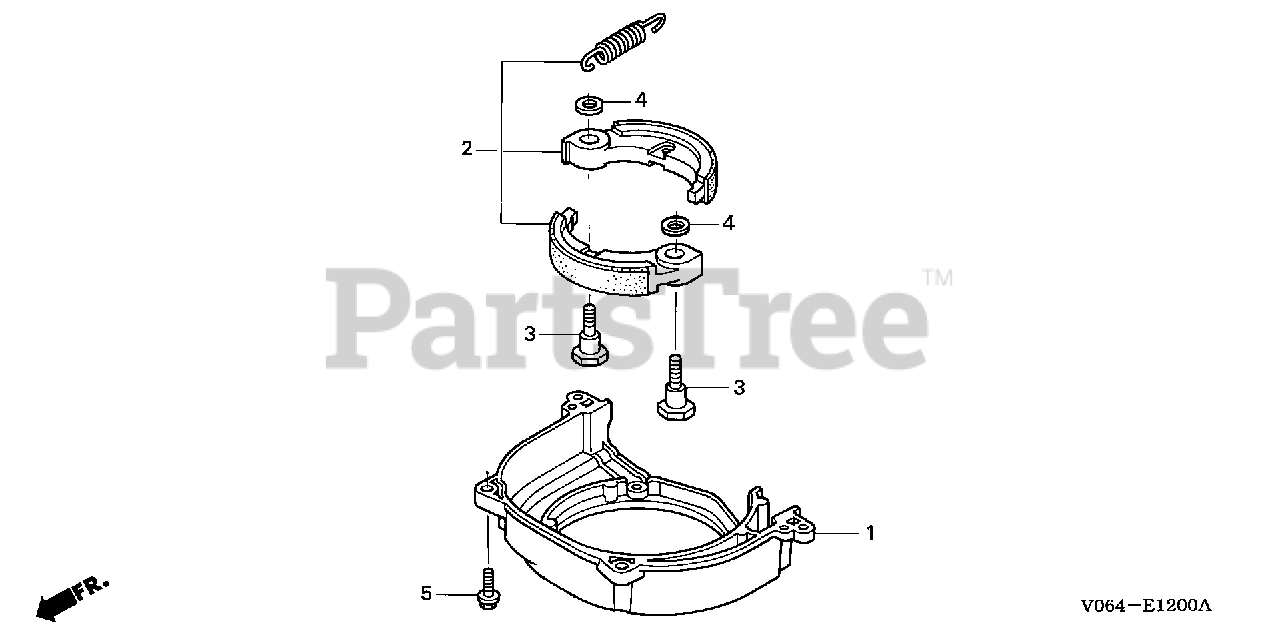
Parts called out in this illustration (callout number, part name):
1	COVER, FAN
2	CLUTCH ASSY.
3	BOLT, CLUTCH (8MM)
4	WASHER, CLUTCH (8X17)
5	BOLT, FLANGE (5X18)
